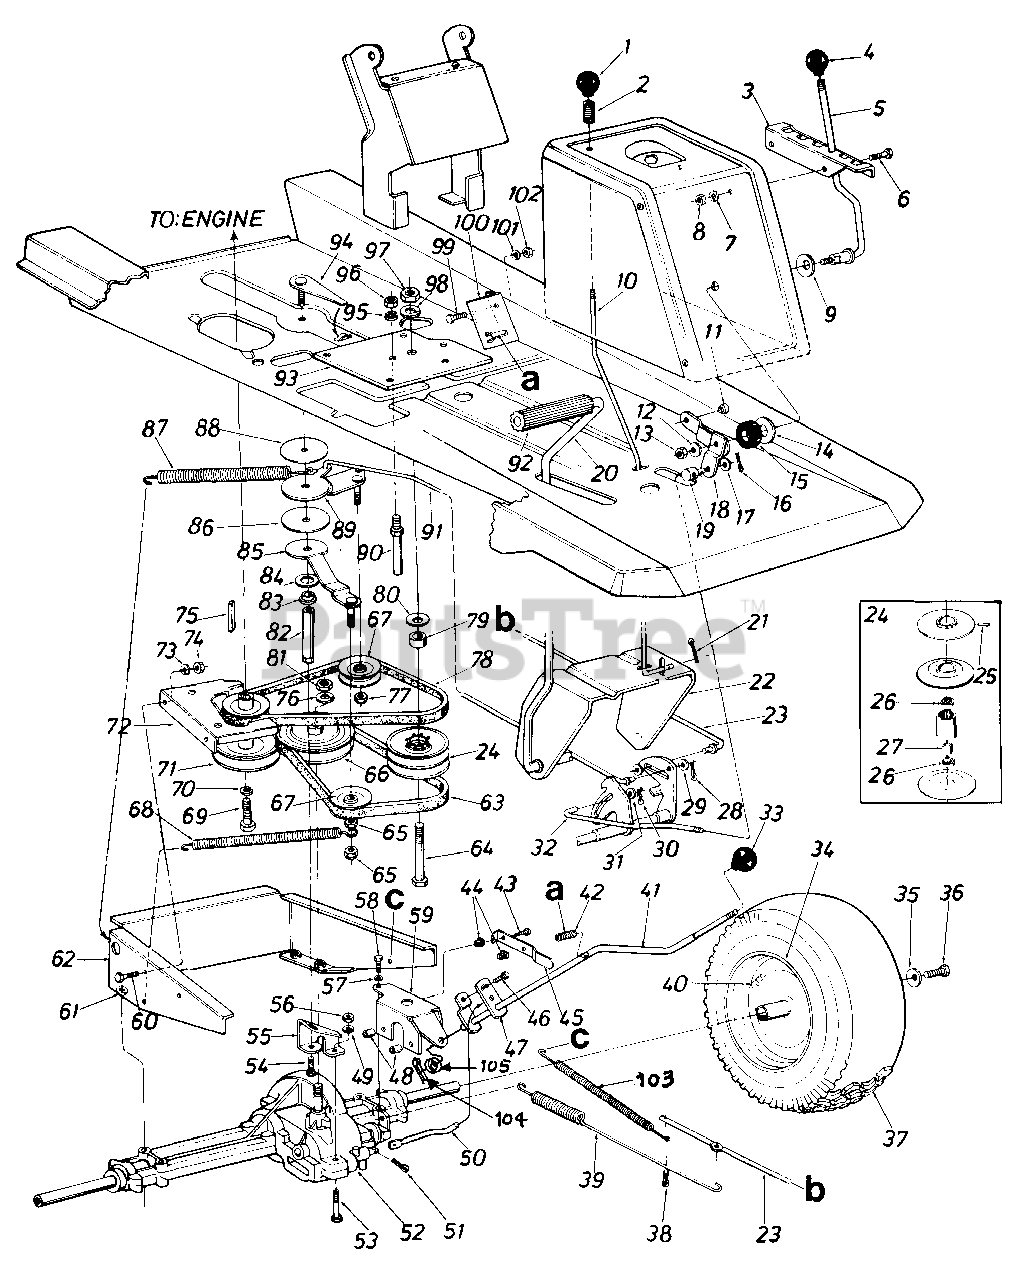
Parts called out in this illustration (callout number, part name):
1	Ball Knob 1/4-20 Thd. 1.25"
2	Compression Spring
5	Speed Control Lever
6	Truss Mach. Scr. 5/16-18 x .75 " Lg .*
7	L-Wash. 5/16" I.D.*
8	Hex Nut 5/16-18 Thd.*
9	Bell-Wash. .345" I.D. x .88"
10	Brake Locking Rod
12	Bell-Wash. .345" I.D. x .08"
13	Hex Cent. L-Nut 5/16-18 Thd.
14	Fl-Wash. .531" I.D. x 1.25" O.D.
15	Rubber Wash. .50" I.D. x 1.25" O.D.
16	Intern. Cotter Pin 1/2" Dia.
17	Fl-Wash. .34" I.D. x .68" O.D.
18	Speed Control Lever Brkt. Ass'y.
19	Ferrule-Engagement
20	Clutch/Brake Pedal Ass'y.
21	Cotter Pin 3/32" Dia. x .75"*
22	Clutch/Brake Pedal Ass'y.
23	Brake Rod
24	Varable Speed Pulley Ass'y.
25	Spring Pin Spir. 5/32" Dia. x .62" Lg.
26	Ball Brg. .50" I.D. x 1.38"
27	Spacer .50" I.D. x 1.00" Lg.
28	Cotter Pin 1/8" Dia. x 1.25"*
29	Fl-Wash. .34" I.D. x .60" O.D.
30	Intern. Cot-Pin 5/16" Dia.
31	Fl-Wash. .34" I.D. x .60" O.D.
32	Speed Control Rod
33	Ball Knob
34	Rear Wheel Rim Only
35	Bell-Wash. .345" I.D. x .88"
36	Hex L-Bolt 5/16-24 x .75" Lg.
37	Rear Wheel Ass'y.-Comp.
38	Cotter Pin 1/8" Dia. x 1.25"*
39	Extension Spring 17.0" Lg.
40	Air Valve
43	C Sink ABS-Tap Scr. #8 x .50" Lg.
44	Push-in Nut #10
45	Spring Switch
46	Hex Bolt 1/4-20 x .50" Lg.*
47	Shift Lever Adjusting Link
48	Spacer .256" I.D. x .87" Lg.
49	L-Wash. 1/4" I.D.
50	Shift Rod
51	Intern. Cotter Pin
52	Transaxle
53	Hex Bolt 1/4-20 x 1.75" Lg.*
54	Hex Bolt 3/8-24 x .75" Lg.
55	Torque Rod Bracket
56	Hex Nut 1/4-20 Thd.
57	L-Wash. 1/4" I.D.
58	Self-Tap Mach. Scr. Type "C" 1/4-20 x 1.37" Lg.
59	Shift Lever Support Brkt.
60	Hex Bolt 1/4-20 x 1.00" Lg.
61	Hex Nut 5/16-18 Thd.
62	Transaxle Support Ass'y.
63	V-Belt 5/8 x 38.0" Lg.
64	Hex Bolt 1/2-13 x 4" Lg.
65	Hex Ins. L-Nut 3/8-24 Thd.
66	5/8 V-Pulley .500" I.D. x 6"
67	V-Belt Idler .38" I.D. x 3.06"
68	Ext. Spring .50" O.D. x 6.37"
69	Hex Bolt 7/16-20 x 1.00" Lg.
70	L-Wash. 7/16" I.D.
71	Engine Pulley .500" O.D. & 3.56" O.D.
72	Upper Eng. Belt Guard
73	L-Wash. 1/4" I.D.*
74	Hex Nut 1/4-20 Thd.*
75	Sq.-Key 1/4" x 2.00" Lg.
76	L-Wash. 1/2" I.D.*
77	Hex Ins. L-Nut 3/8-24 Thd.
78	V-Belt 5/8 x 35.0" Lg.
79	Spacer .501" I.D. x .775 Lg.
80	Bell-Wash. .505" I.D. x 1.00"
81	Hex Nut 1/2-13 Thd.*
82	Torque Rod
83	Flange Bearing .378
84	Fl-Wash. .640" I.D. x 1.24"
85	Idler Bracket Ass'y.
86	Thrust Wash. .635" I.D.
87	Extension Spring 8.0" Lg.
88	Thrust Wash. .385" I.D.
89	Idler Bracket Ass'y. For Clutch
90	Belt Guard Pin 1/4" Dia.
91	Clutch Rod
92	Foot Pad
93	Mounting Bracket Variable Pulley
96	Hex Nut 1/4-20 Thd.*
97	Hex Nut 1/2-13 Thd.
98	L-Wash. 1/2" I.D.
99	Hex Bolt 5/16-18 x .75" Lg.*
100	Shift Lever Spring Brkt.
101	L-Wash. 5/16" I.D.
102	Hex Nut 5/16-18 Thd.
103	Extension Spring
104	Cotter Pin
105	Fl-Wash. .469" I.D. x .88"6-2-51
